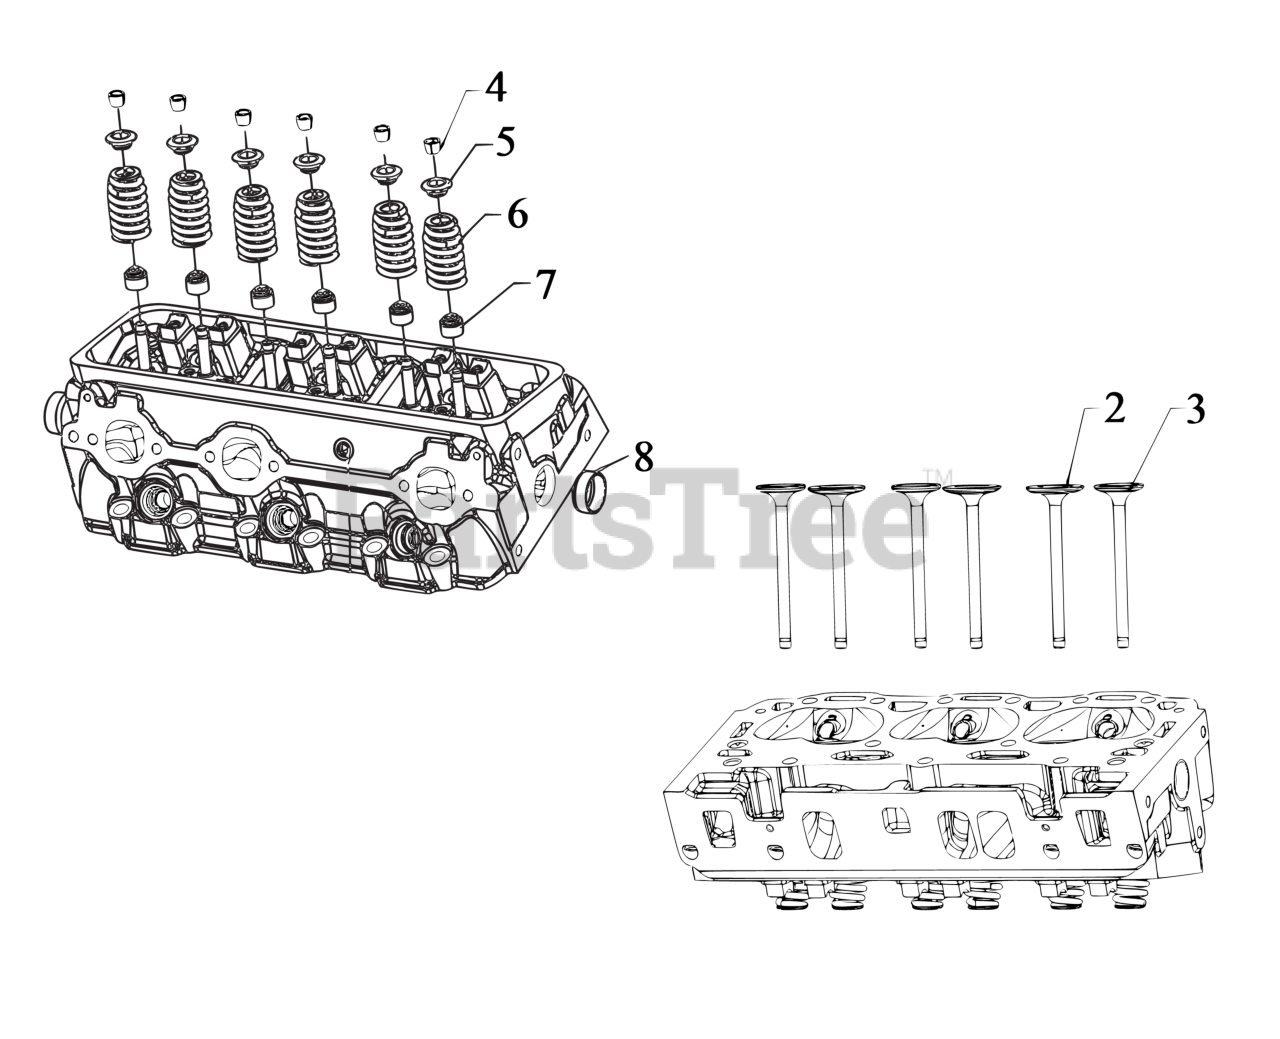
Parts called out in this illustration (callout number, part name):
2	*VALVE, INTAKE
3	*VALVE, EXHAUST
4	*KEY
5	*RETAINER, Valve Spring
6	*SPRING
7	*SEAL, VALVE STEM
